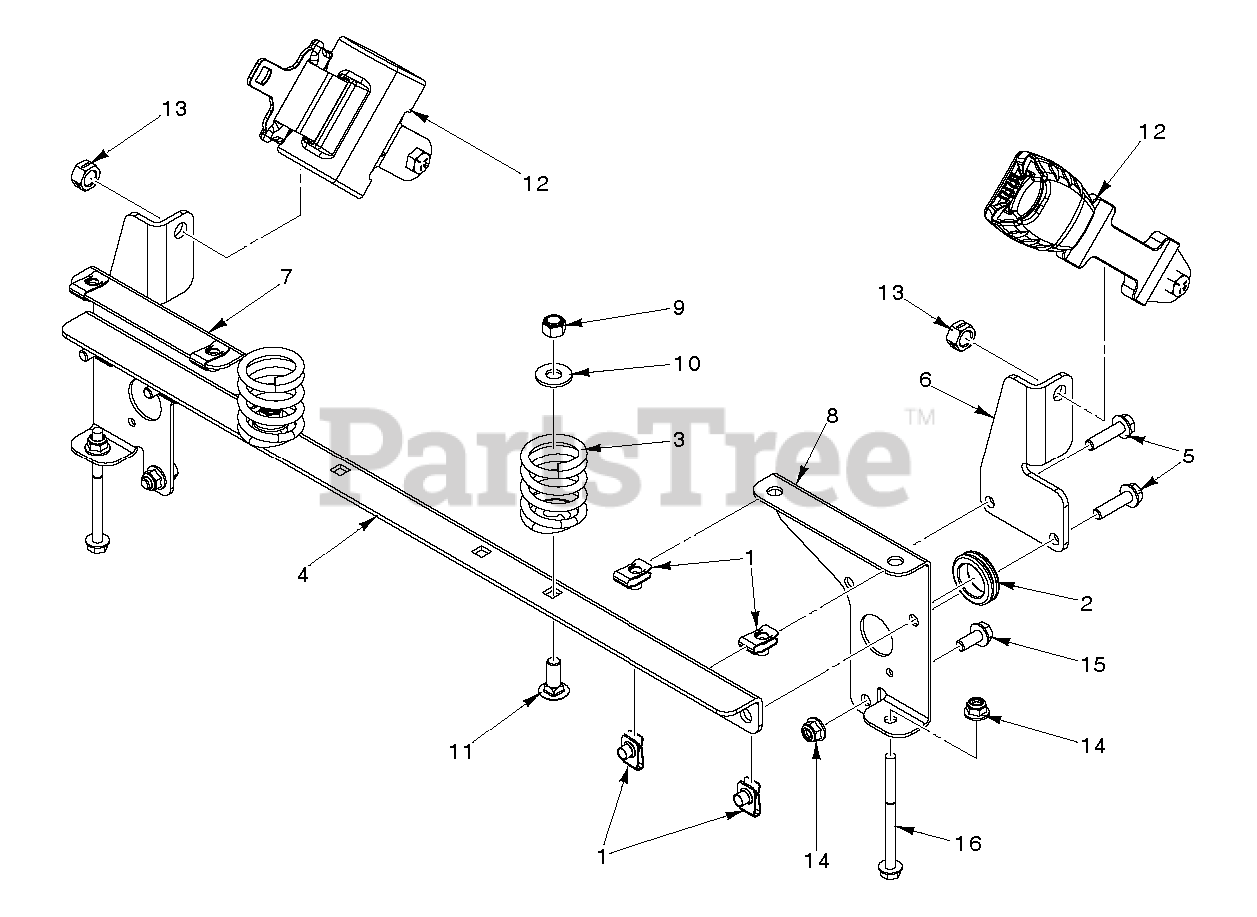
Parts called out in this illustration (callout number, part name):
1	U-CLIP 5/16-18 NUT RETAINER
2	RUBBER GROMMET
6	MOUNT.SEAT.BELT.BLACK
7	SUPPORT.RT.BLK
8	SUPPORT.LT.BLK
10	GSPW Washers
13	NUT HEX 7/16F LOCK RP
14	NUT HEXAGON FLANGE 5/16-18 ST
16	Husqvarna TBD
